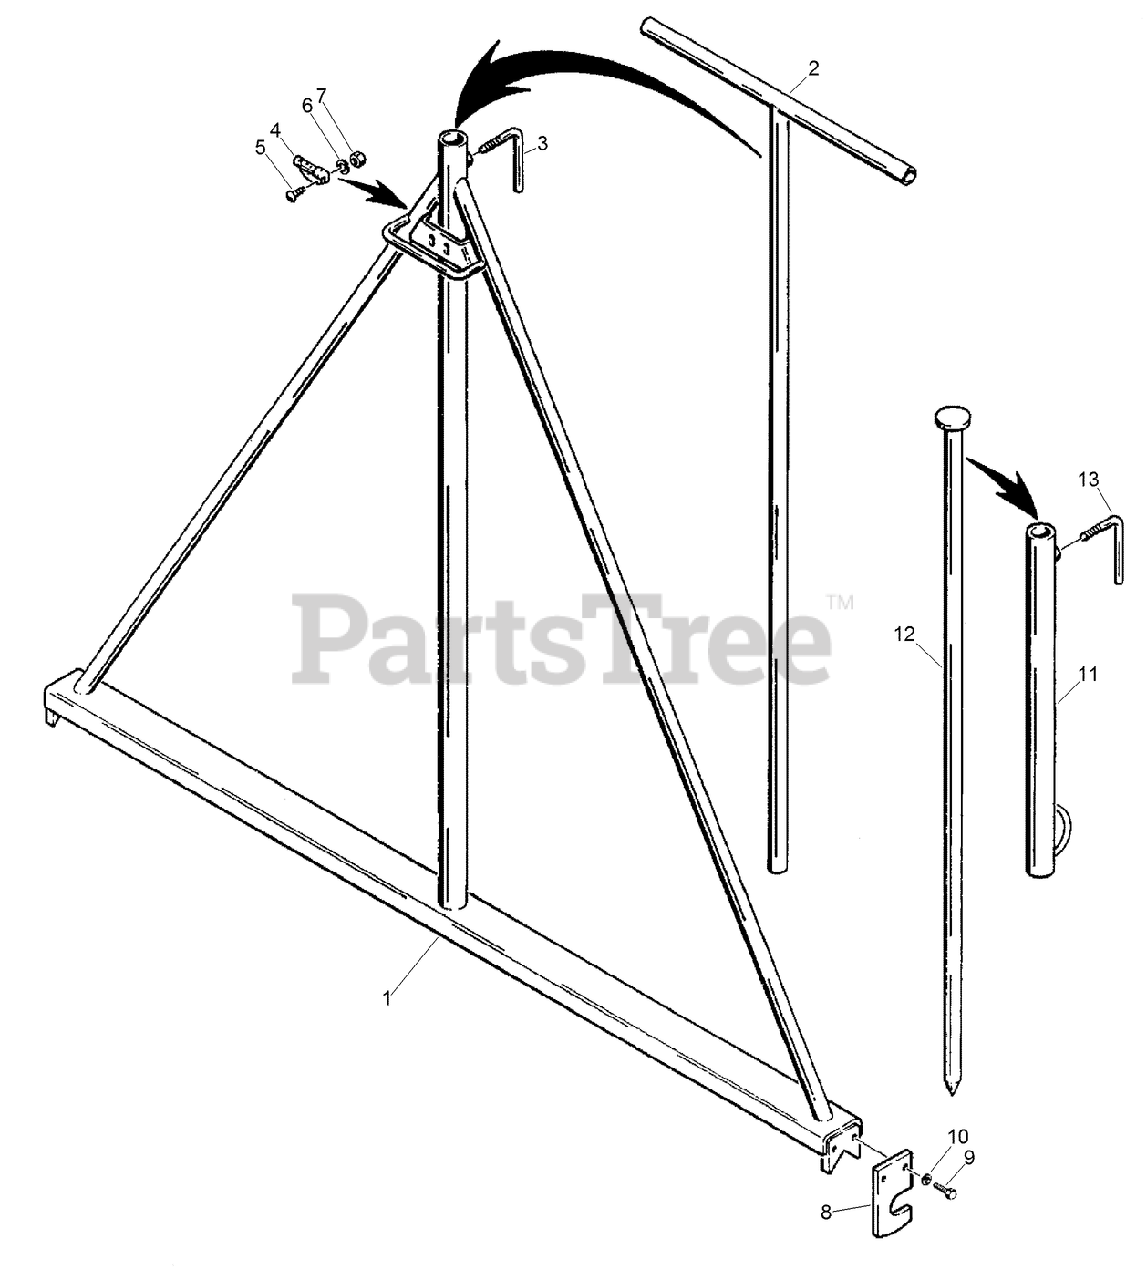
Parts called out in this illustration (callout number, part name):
1	FRAME-drill stem level
2	HANDLE-frame
3	LOCK-handle adjustment
4	LEVEL-frame
5	SCREW-machine, pan head slotted, No. 4 NC x 5/8 inch
6	WASHER-lock, No. 4
7	NUT-hex, No. 4 NC
8	GUIDE-drill stem
9	SCREW-HH
10	WASHER-Lock, 5/16 inch
11	TUBE-guide anchor (components of 185583A1 Hydra-Borer basic application kit)
12	SHAFT-guide anchor (components of 185583A1 Hydra-Borer basic application kit)
13	LOCK-handle adjustment
